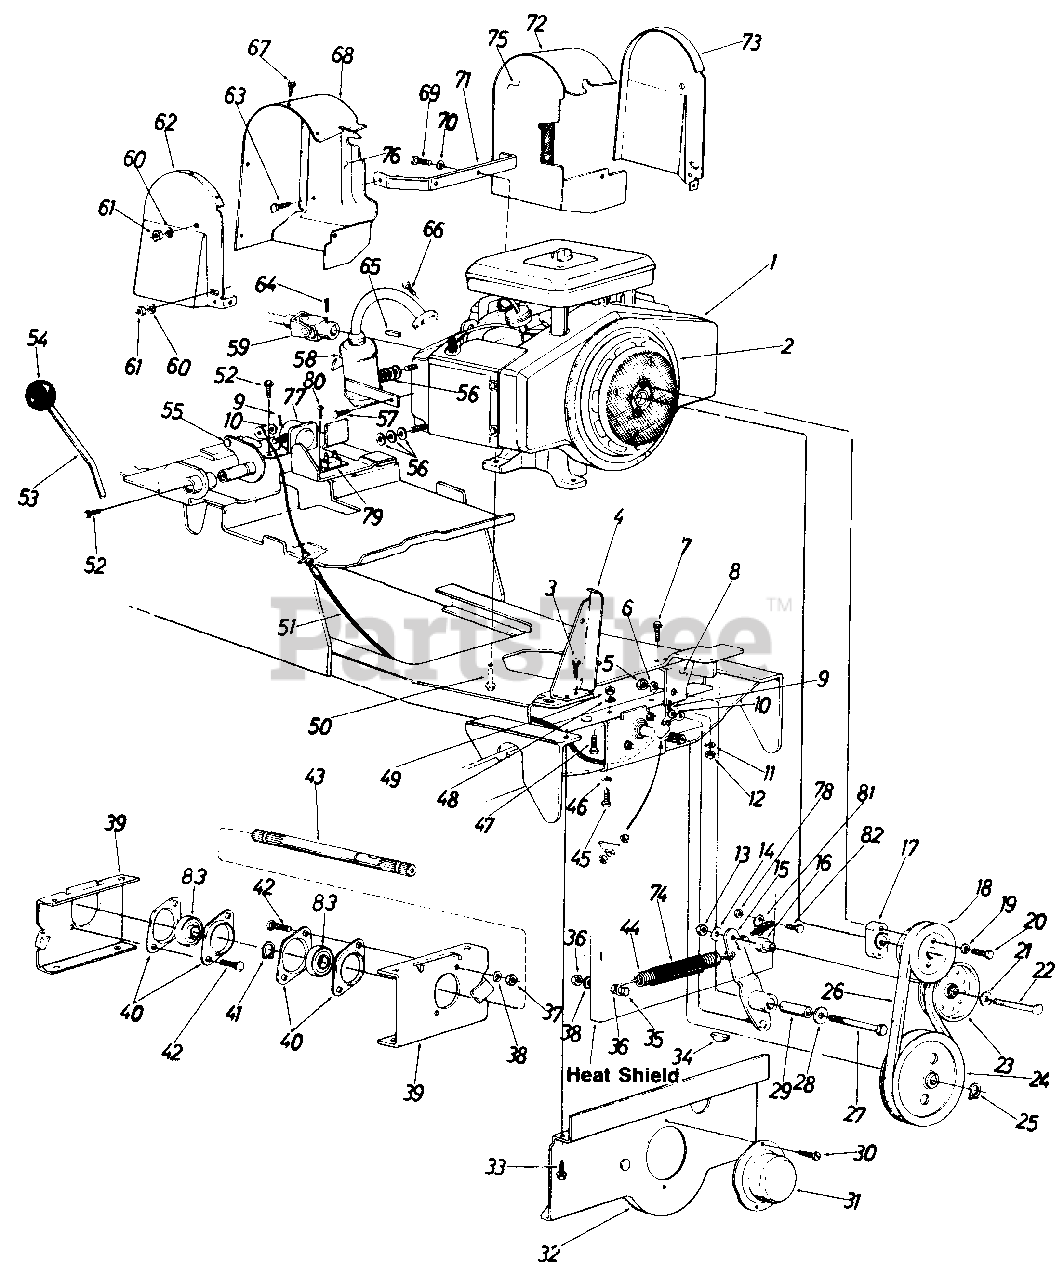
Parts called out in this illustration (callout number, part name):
1	Engine
2	Mylar Foam Strip
3	Hex Wash. Hd. Self-Tap Scr. 1/4-20 x .75" Lg.
6	L-Wash. 3/8" Scr.
7	Hex Wash. Hd. Self-Tap Scr. 5/16-18 x .75" Lg.
10	Fl-Wash 38" I.D. x 1.25 O. D x . 1 0 Thk.
11	L-Wash. 3/8" Scr.
12	Hex Nut 3/8-16 Thd.
13	Hex Nut 3/8-16 Thd.
14	Fl-Wash. .38 I.D. x 1.25" O.D. x .10 Thk.
17	Pulley Spacer
18	1/2" V-Pulley 4.75" O.D.
19	L-Wash. 3/8" Scr. H.D.
20	Hex Scr. 3/8-16 x 2.00" Lg
21	Fl-Wash. .38" I.D. x 1.25 O.D. x .010 Thk.
22	Hex Scr. 3/8-16 x 2.50" Lg.
23	Flat Idler Pulley
24	1/2" V-Pulley 7 00n O.D.
25	Snap Ring
26	"V"-Belt 1/2 " x 41 " Lg.
27	Hex Scr. 3/8-16 x 2.50" Lg.
28	Fl-Wash. .38" I.D. x 1.25" O.D. x .010
29	Spacer .375" I.D. x .62" O.D. x 1.830 Lg.
30	Hex "B" Tap Scr. #10 x .50" Lg.
34	#91 Hi-Pro Key
35	Hex Scr. 5/16-18 x 1.25" Lg.
36	Hex Nut 5/16-18 Thd.
37	Hex Nut 5/16-18 Thd.
38	L-Wash. 5/16" Scr.
39	PTO Brg. Retainer Brkt.
40	1.00" Dia. Brg. w/Flangette
41	Snap Ring
42	Carr. Bolt 5/16-18 x .75" Lg.
43	Spline Shaft
44	Extension Spring
45	Hex Scr. 3/8-16 x 1.00n Lg.
46	L-Wash. 3/8" Scr.
47	Hex Scr. 3/8-16 x 1 oon Lg.
48	L-Wash. 3/8" Scr.
49	Hex Nut 3/8-16 Thd.
50	Hex Wash. Hd. Self-Tap Scr. 3/8-16 x 1.25" Lg.
51	PTO Control Cable
52	Hex Wash. Hd. Self-Tap Scr. 1/4-20 x .50"
53	PTO Handle
54	Ball Knob
55	PTO Actuator Lever Ass'y.
56	Fl-Wash. .312" I.D. x 1.620n O.D. x .060
57	Hex Wash. Hd. Self-Tap Scr. 1/4-20 x .50" Lg.
58	Muffler Ass'y. Comp. R.H.
59	Universal Joint Ass'y. Comp.
60	Fl-Wash. .312" I.D. x .630" O.D. x .063
61	Hex Nut 5/16-18 Thd.
62	Shroud Outer R.H.
63	Hex Wash. Hd. Self-Tap Scr. 1/4-20 x .50" Lg.
64	Sq. Hd. Set Scr. 5/16-18 x .38" Lg.
65	Sq. Key 1/4" x 2.00" Lg.
66	Hex Wash. Hd. Scr. 1/4-20 x 5/8" Lg. Grade 5
67	Hex "AB" Tap Scr. #10 x 50n Lg
68	Shroud Cover R.H.
69	Hex Scr. 5/16-24 x 75" Lg.
70	L-Wash. 5/16" Scr.
71	Shroud Support Brkt.
72	Shroud Cover L.H.
73	Shroud Outer L.H.
74	Spring Cover Tubing
75	Shroud Inner Ass'y. L.H.
76	Shroud Inner Ass'y. R.H.
77	Solenoid
78	Hex Scr. 1/4-20 x 1/2" Lg.
79	Circuit Breaker
80	Truss Mach. Scr. #10 x 50" Lg.
81	Safety Switch
82	L-Wash. 1/4" Scr.
83	Ball Bearing
